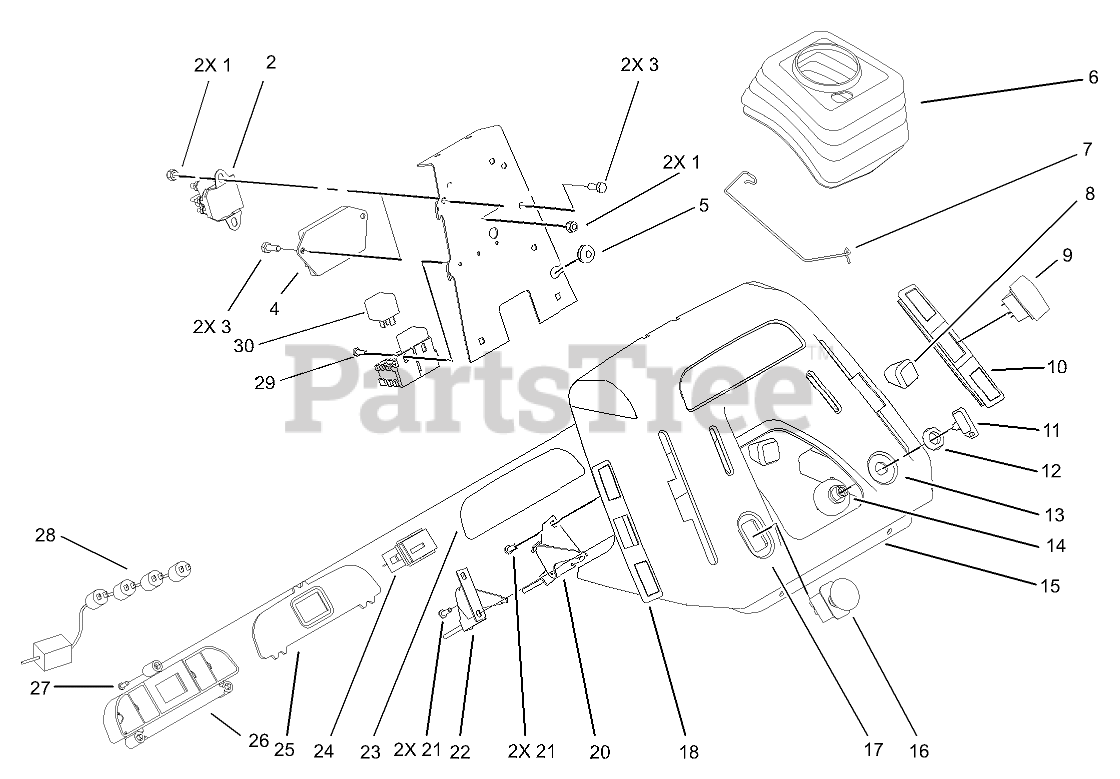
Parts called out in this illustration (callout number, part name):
1	NUT-LOCK, NI
2	SOLENOID-STARTER
3	SCREW-HH
4	MODULE-NMIR, LOW BATTERY
5	GROMMET-RUBBER
6	BOOT-STEERING
7	CLIP-BOOT
9	SWITCH-CRUISE
10	COVER-SLOT, RH
11	KEY-IGNITION
13	DECAL-THROTTLE, IGNITION
14	SWITCH-IGNITION
16	SWITCH-PTO
17	DECAL-PTO / CHOKE
18	COVER-SLOT, LH
20	CONTROL-THROTTLE (TWIN)
22	CHOKE CONTROL ASM
23	DECAL-LENS, DASH
24	HOURMETER
25	LENS-DASH
26	HOUSING-LIGHT, INDICATOR
27	SCREW
28	HARNESS-4 LAMP
29	SCREW-PPHTF
30	RELAY
